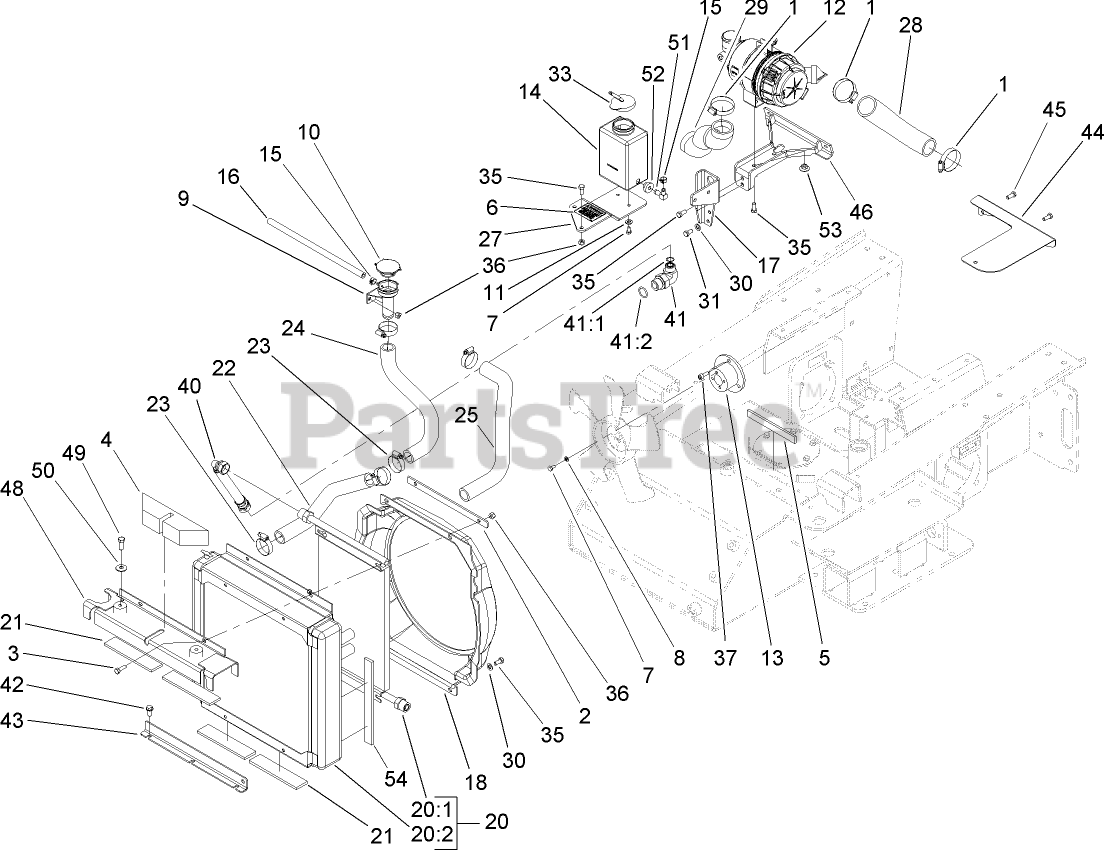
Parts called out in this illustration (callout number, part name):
1	CLAMP-HOSE
2	PLATE-BACKING
3	SCREW-HH
4	SEAL-FOAM
5	PAD-RUBBER
6	DECAL-RADIATOR, FILL
7	SCREW-HH
8	WASHER-LOCK
9	TUBE-FILLER, RADIATOR
10	CAP-RADIATOR
11	WASHER-FLAT
12	AIR CLEANER ASM
13	SPACER-FAN, MOUNT
14	TANK-OVERFLOW
15	CLAMP-HOSE
16	HOSE-LP
17	MOUNT-FILTER, AIR
18	SHROUD-FAN
20	RADIATOR AND OIL COOLER ASM
20:1	COOLER-OIL, HYD
20:2	RADIATOR
21	PAD-RUBBER
22	HOSE-RADIATOR
23	CLAMP-HOSE
24	HOSE-RADIATOR
25	HOSE-RADIATOR
27	BRACKET-TANK, OVERFLOW
28	HOSE-AIR, INLET
29	HOSE-AIR
30	WASHER-PLAIN
31	BOLT
33	CAP-TANK, OVERFLOW
35	SCREW-HH
36	NUT-LOCK, NI
37	SCREW-CAP, HSH
40	HYD HOSE ASM
41	FITTING-ELBOW 90
41:1	O-RING
41:2	O-RING
42	SCREW-HWHTF
43	MOUNT-RADIATOR
44	PLATE-BAFFLE, STARTER
45	SCREW-HH
46	BRACKET ASM
48	BRACKET-RADIATOR
49	SCREW-HH
50	WASHER-SPRING
51	FITTING-ELBOW
52	BUSHING-VALVE, FUEL
53	NUT-HF
54	FOAM-SEAL
